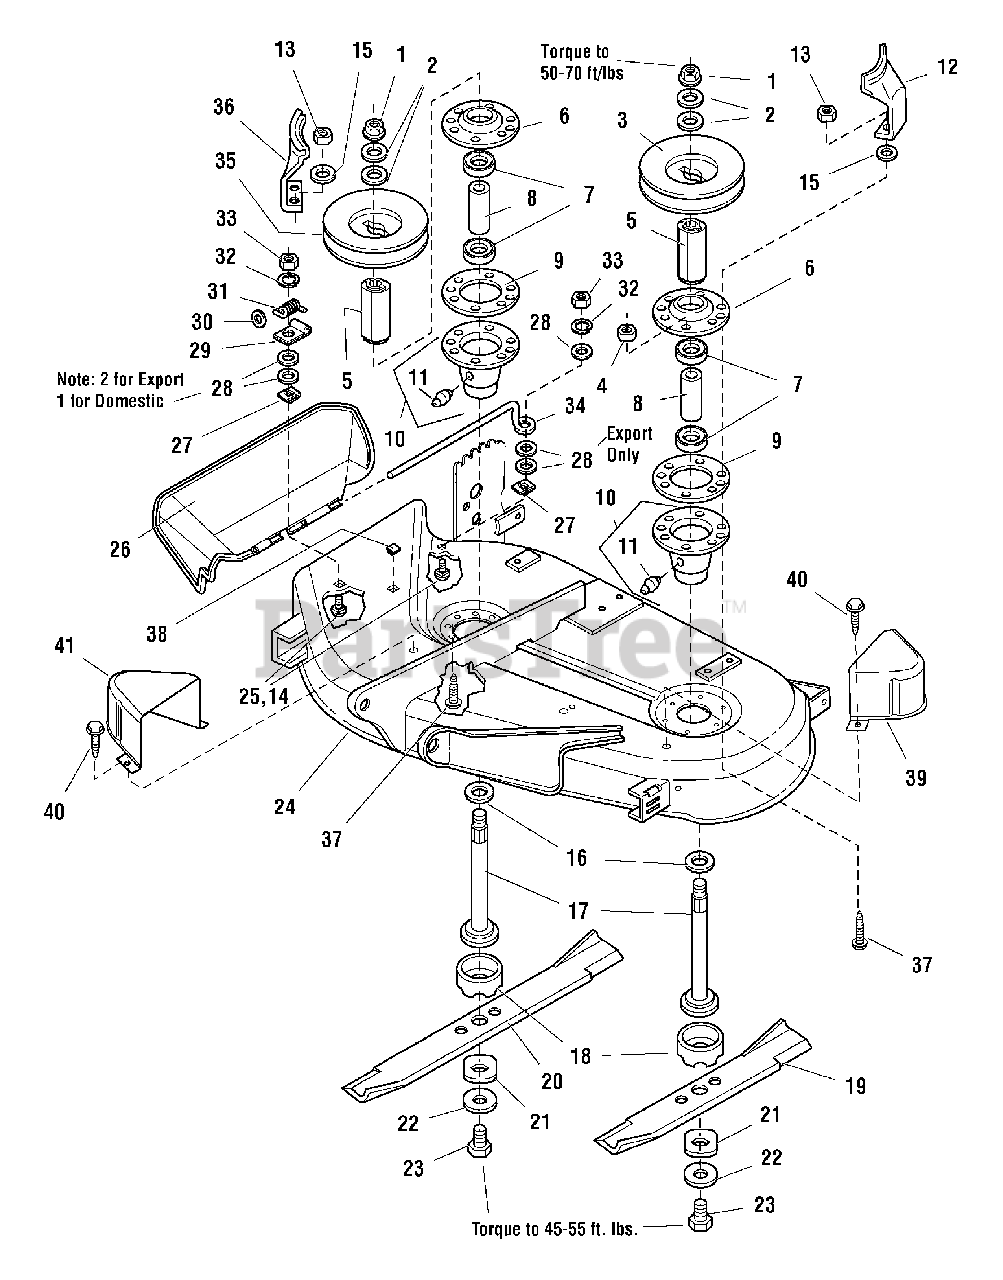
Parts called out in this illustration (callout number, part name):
1	NUT, Hex, Flange, 9/16-8
2	WASHER, Belleville
3	PULLEY, LH, 4" OD
4	NUT, Hex, 5/16-18
6	COVER, Arbor Housing
9	GASKET, Foam
10	HOUSING ASSEMBLY, Arbor Bottom, w/Lube Fitting
11	FITTING, Grease
12	STOP, Belt, LH
13	NUT, Hex, Whiz Lock, 5/16-18
14	CARRIAGE BOLT, 1/4-20 x 1-1/4
15	WASHER, Flat, 3/8
17	SHAFT, Arbor
18	SHIELD, Grass, Lower
19	BLADE, Mower, 16-1/8
20	BLADE, Mower, 22-1/4
21	WASHER, Hex
22	WASHER, Spring
23	CAPSCREW, Hex Head, 7/16-14 x -1/4
24	MOWER DECK HOUSING, 38", Orange
24	MOWER DECK HOUSING, 38", Red
25	CARRIAGE BOLT, 1/4-20 x 7/8
26	DEFLECTOR, Plastic
27	NUT, Push On
28	CARRIAGE BOLT, 1/4-20 x 1-1/4
30	WASHER, Plain, 5/16
32	LOCKWASHER, 1/4
33	NUT, Hex, 1/4-20
34	ROD, Deflector, Front
35	PULLEY, RH, 5-1/4OD
36	STOP, Belt, RH
37	CAPSCREW, Taptite Hex Washer Head, 5/16-18 x 1
38	PLUG, Plastic
39	COVER ASSEMBLY, LH
40	CARRIAGE BOLT, 1/4-20 x 1-1/4
41	COVER ASSEMBLY, RH
